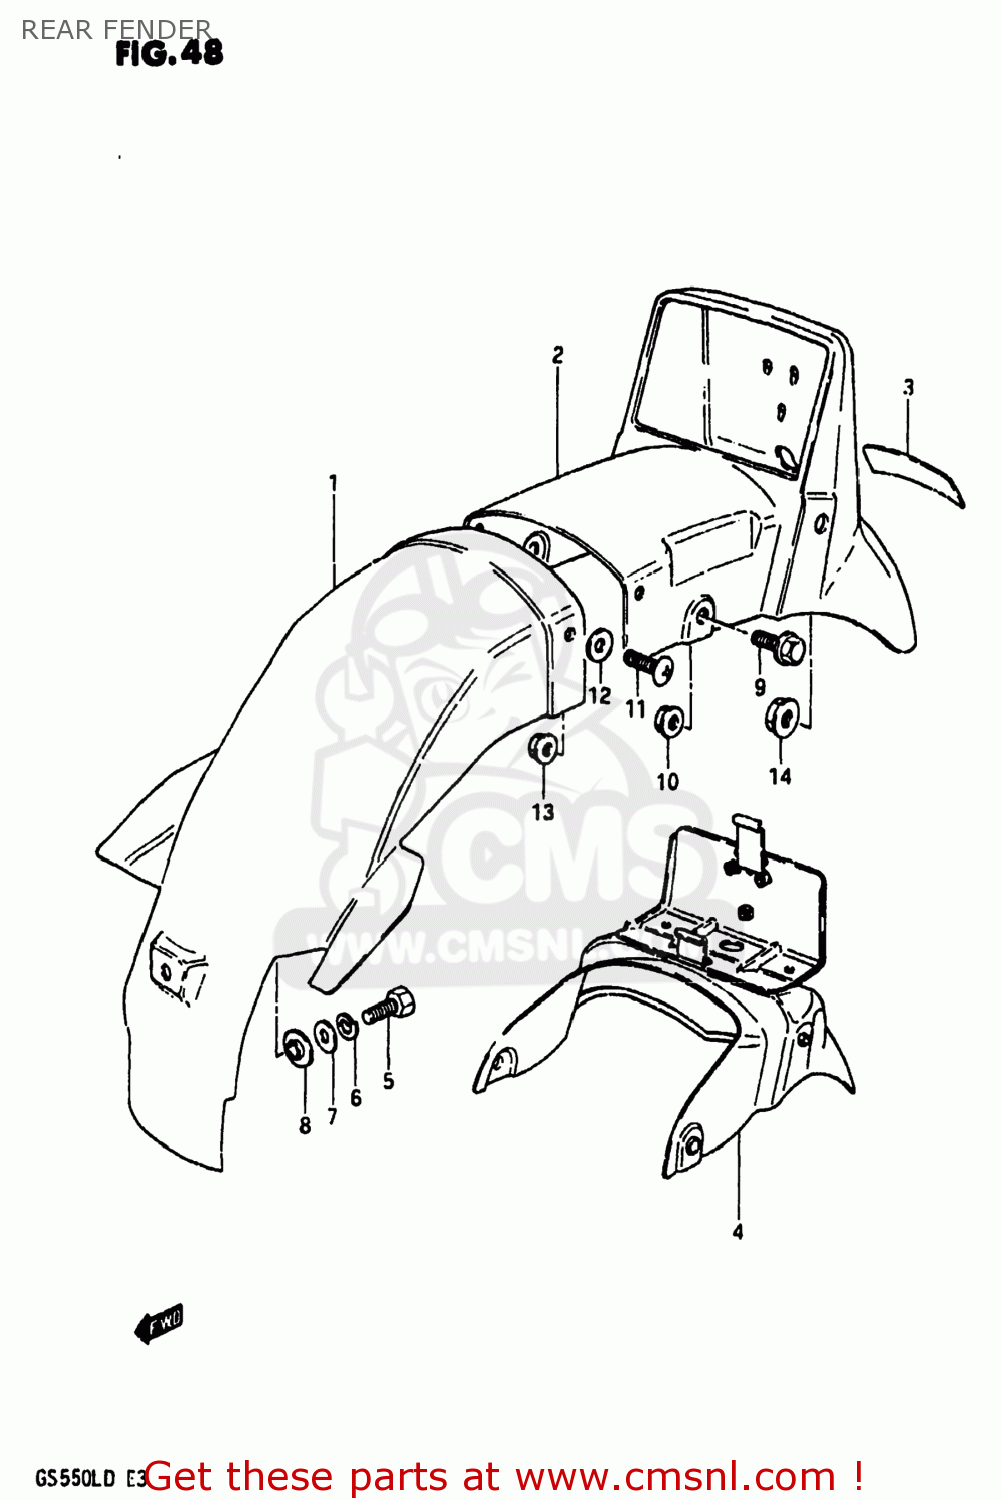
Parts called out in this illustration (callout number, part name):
1	BODY,REAR FENDER,FRONT
2	FENDER,REAR
3	EMBLEM,REAR FENDER
4	REINFORCEMENT,REAR FENDER
5	BOLT, UPPER
6	LOCK WASHER
7	WASHER 6MM
8	WASHER
9	BOLT
10	NUT
11	SCREW
12	WASHER
13	NUT
14	NUT
